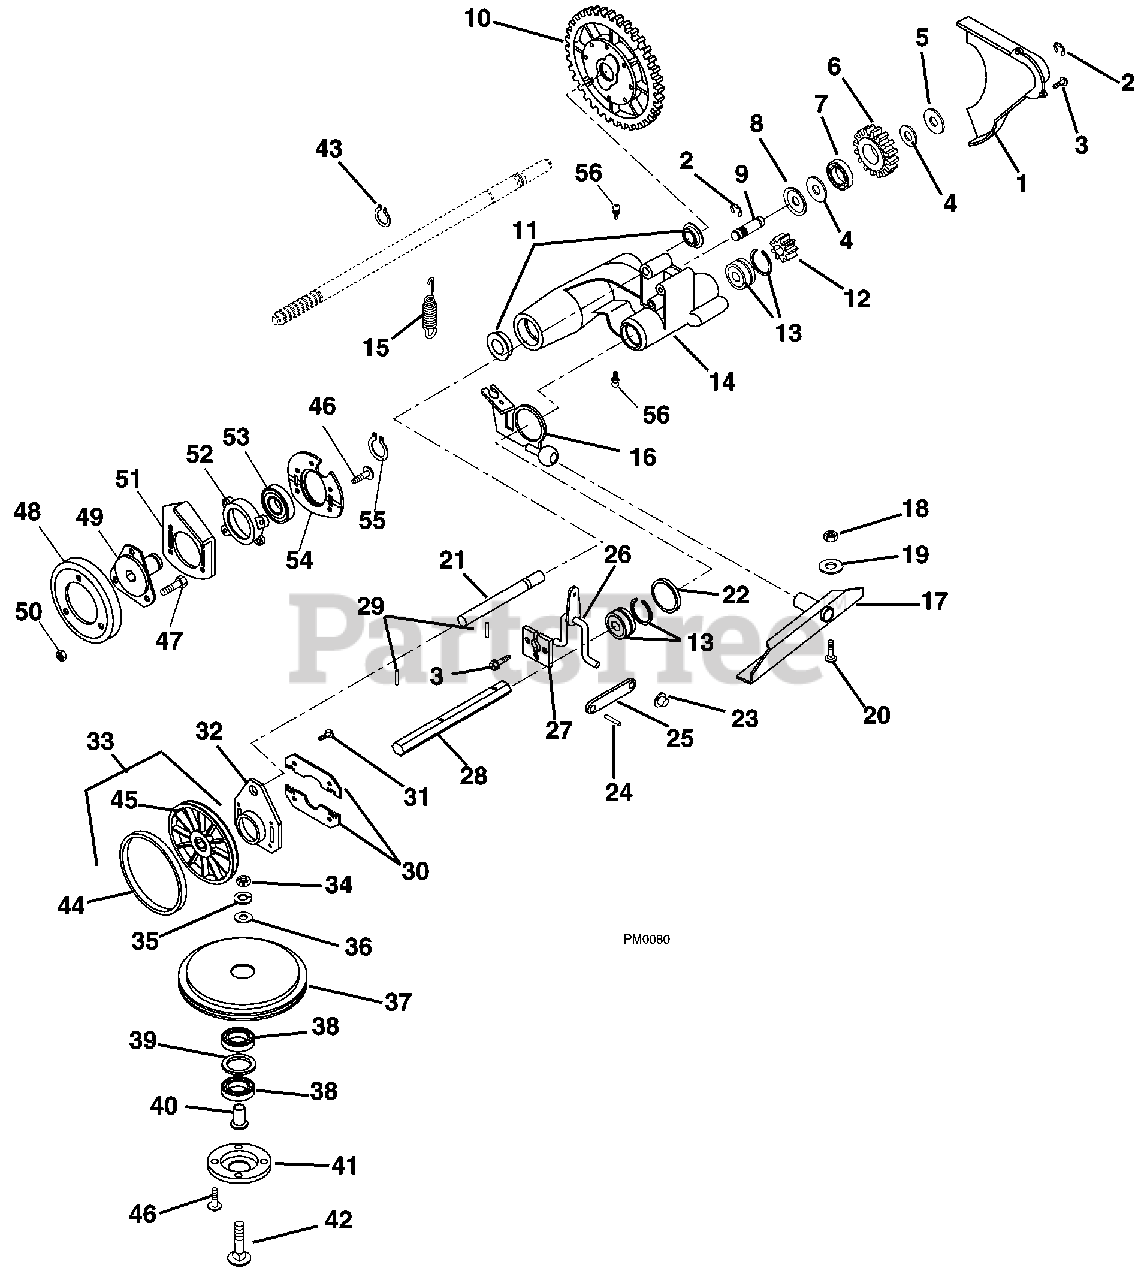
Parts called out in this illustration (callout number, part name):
1	Gear Cover
2	Ring-Retaining-External .438 x .035
3	Screw-Tapping 12-24 x .50 Hex Washer Head
4	Washer - Flat - Steel .520 x .827 x .062
5	Washer - Flat - Steel .531 x 1.00 x .063
6	Idler Gear
7	Bearing - Ball .50 x 1.38 x .437
9	Idler Shaft
10	Differential Assembly
11	Bearing-Ball .625 x 1.383 x .50 (600 C)
12	Gear-Pinion
13	Bearing - Ball .562 x 1.375 x .437 (600 C)
14	Drive Mount
15	Spring-Tension .051 x .60 x 2.25
16	Drive Actuator Weldment
17	Pivot Channel Weldment
18	Nut-Locking-Center .31-18
19	Washer-Flat-Steel .344 x .688 x .065
20	Bolt-Round Head Square Short Neck .31-18 x .62
22	Washer - Flat - Steel 1.390 x 2.00 x .020
23	Push Nut .25
24	Pin-Roll .125 x .50 (580 R, 580 RS, 580 RSE, 580 RSW, 580 BBC)
25	Shift Link
26	Shift Arm Weldment
27	Retainer Plate
29	Pin - Roll .188 x .88
30	Thrust Plate (580 R, 580 RS, 580 RSE, 580 RSW, 580 BBC)
31	Screw-Tapping 10-24 x .375 Hex Washer Head (580 R, 580 RS, 580 RSE, 580 RSW, 580 BBC)
32	Guide-Plate (580 R, 580 RS, 580 RSE, 580 RSW, 580 BBC)
33	Friction Wheel Assembly (580 R, 580 RS, 580 RSE, 580 RSW, 580 BBC)
34	Nut-Hex .31-18
35	Washer-Locking .312 x .097 Heavy
36	Washer Flat-Steel .328 x .875 x .062
37	Friction Sheave
38	Bearing-Ball .625 x 1.375 x .43
39	Washer- Flat-Steel 1.062 x 1.344 x .032
40	Spindle, Bearing
41	Bearing, Retainer
42	Bolt-Round Head Square Neck .31-18 x 1.75 Grade 5 (600 C)
43	Ring-Retaining-External .579 x .930
44	Friction Ring (580 R, 580 RS, 580 RSE, 580 RSW, 580 BBC)
45	Friction Wheel Hub (580 R, 580 RS, 580 RSE, 580 RSW, 580 BBC)
46	Screw-Tapping 12-24 x .50 Hex Washer Head (580 R, 580 RS, 580 RSE, 580 RSW, 580 BBC)
47	Bolt-Hex .25-20 x .50 Grade 5 (600 C)
48	Disc, Friction (600 C)
49	Hub, Friction Wheel (600 C)
50	Nut-Locking-Center .25-20 (600 C)
51	Bearing Plate (600 C)
52	Bearing Retainer (600 C)
53	Bearing Ball 1.00 x 2.00 x .56 (600 C)
54	Bearing Retainer (600 C)
55	Ring-Retaining - External 1.00 x .042 (600 C)
56	Fitting-Lube .25-28 x .256 (600 C)
